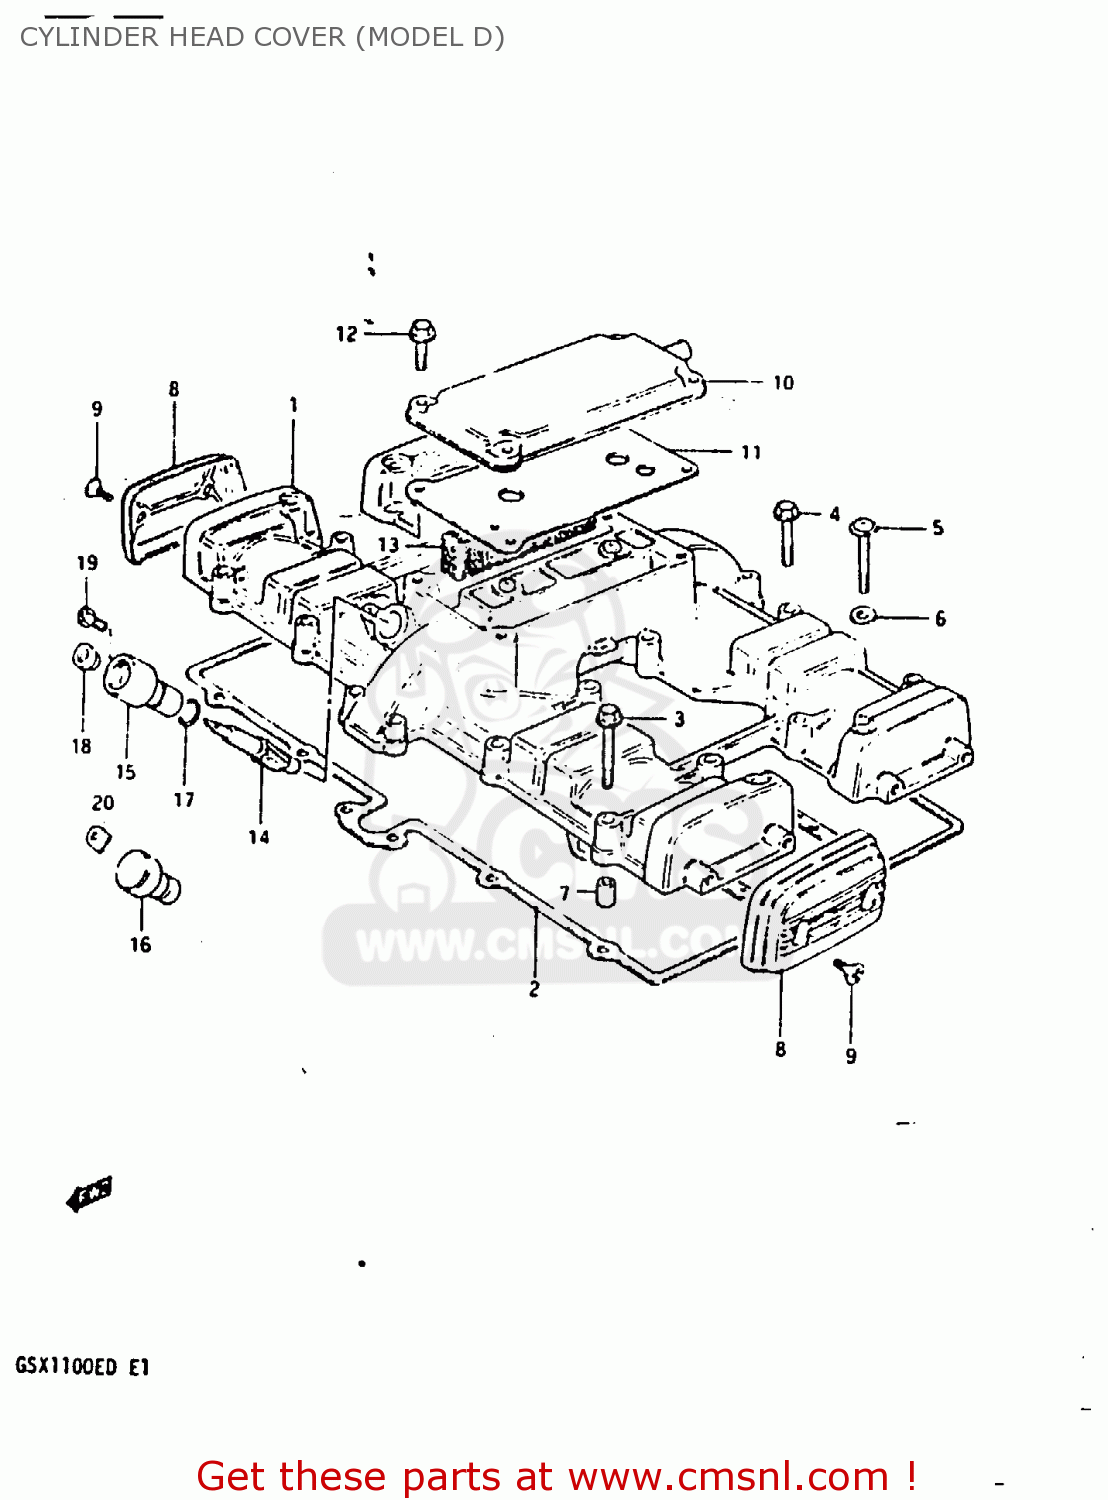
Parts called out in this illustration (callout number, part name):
1	COVER,CYLINDER HEAD
2	GASKET,CYLINDER HEAD COVER
3	BOLT (6X40)
4	BOLT
5	SCREW 6X40
6	GASKET (NAS)
7	PIN(6.2X8X11)
8	CAP,CYLINDER HEAD COVER
9	SCREW(5X12)
10	COVER,BREATHER
11	GASKET (MCA)
12	BOLT
13	COVER,BREATHER
14	GEAR,TACHOMETER DRIVEN
15	SLEEVE,TACHOMETER DRIVE GEAR
16	PLUG,TACH GEAR SLEEVE HOLE
17	SEAL,TACHOMETER DRIVEN
18	SEAL,OIL(5X12X8)
19	SCREW(5X12)
20	PLATE,TACH DRIVE GEAR SLEEVE
